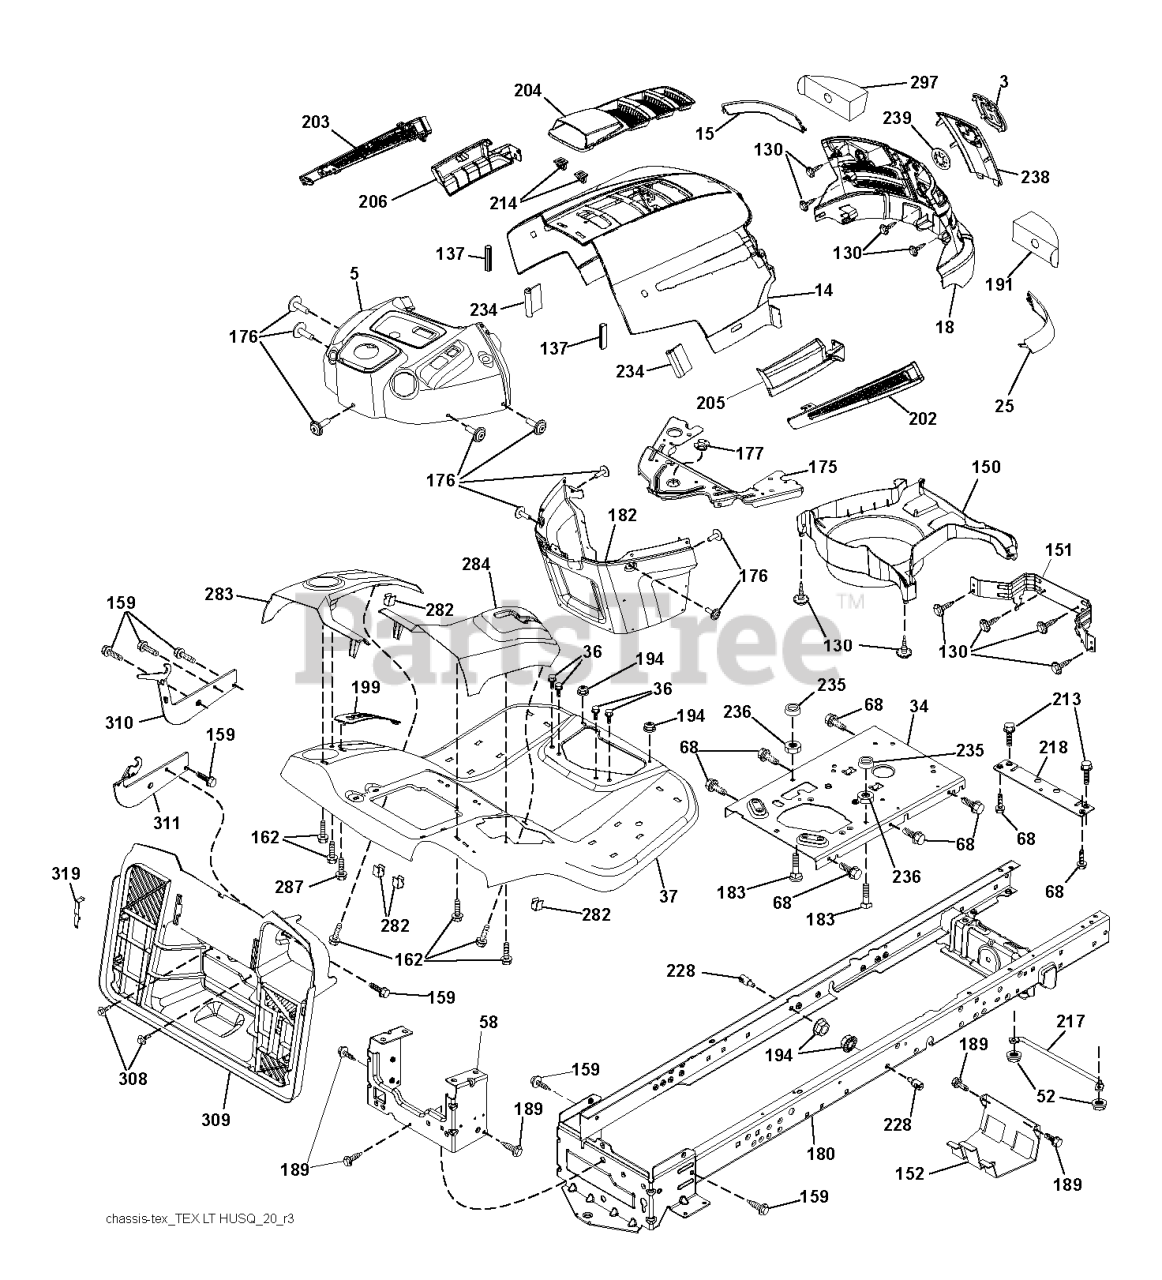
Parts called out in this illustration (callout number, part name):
3	RP LOGO
5	DASH
14	HOOD.HUSQVARNA.LT.MS422
15	LENS.HUSQVARNA LT.LH
18	RP GRILLE/LENS ASM.
25	LENS.HUSQVARNA LT.RH
34	PLATE.ENGINE.WELDED.CHASSIS
36	SCREW 5/16"
37	FENDER.PNT.SRD.30R
52	LOCKNUT
58	DRAWBAR UPPER 2PC SMALL FENDER
68	Screw 5/16-18 x 1/2 Hex, Self Tapping 5/16-18 x 1/2
130	SCREW.#10 X 0.750.BOS
137	BUMPER DASH
151	BRACKET PIVOT
152	SHIELD.BROWNING.W/TEX
159	SCREW, 3/8-16X3/4
162	SCREW.HI-LO.CONSOLE
175	CROSSMEMBER
176	SCREW.#10-24X5/8.RN.QU
177	BUSHING STEERING
180	CHASSIS.WLDMNT.14GA.2PC.18".TI
182	DASH.LOWER.PREDATOR LT
183	BOLT.5/16-18X1-1/4 FULL.THREAD
189	SCREW
191	INSERT REFLECTIVE
194	NUT LOCK HEX FLANGE 5/16-18
199	PLATE DECK LIFT
202	VENT SIDE HOOD LH
203	VENT SIDE HOOD RH
204	VENT TOP HOOD
205	SKIRT SIDE RH
206	SKIRT SIDE LH
213	BOLT
214	CLIP.RETAINER.TINNER.
217	ROD.PIVOT.HOOD
218	X-PIECE.HOOD.STOP.NON/
228	STUD.FASTNER.W/ANTI-ROTATE
234	BUMPER.HOOD.TEX.HUSQVARNA
235	SPACER FENDER
236	NUT.CENTERLOCK.5/16-
238	TRIM
282	CLIP.RETAINER.CONSOLE.LT.HUSQ
283	CONSOLE.DCKLFT.SRD.BGR
287	SCREW 1/4X20
297	INSERT.REFLECTIVE.RH.
308	BOLT.5/16-18UNCX3/4 W/SEMS.BLK
309	BACKPLATE.BAGGER.V2.SRD
310	Bracket Hangar Bag LH
311	Bracket Hangar Bag RH
319	BRACKET.ACTUATOR.BAGGER.SRD
